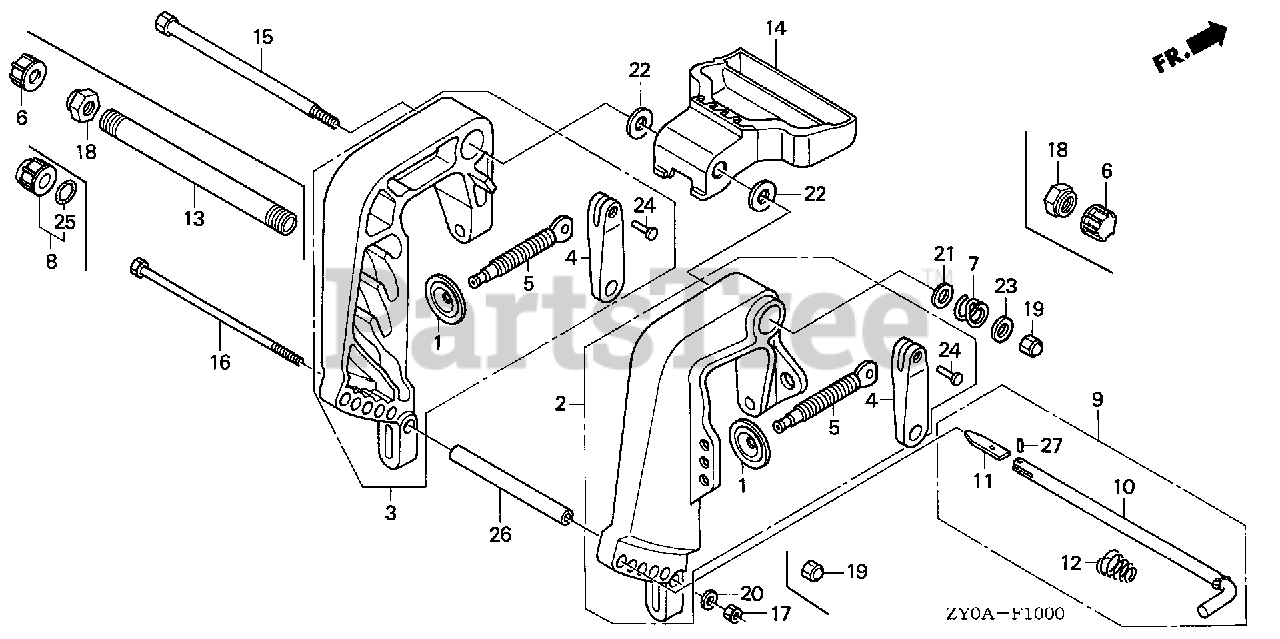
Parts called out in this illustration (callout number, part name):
1	PLATE, PUSH
2	BRACKET, R. STERN *NH282MU* (OYSTER SILVER METALLIC-U)
3	BRACKET, L. STERN *NH282MU* (OYSTER SILVER METALLIC-U)
4	GRIP, CLAMP
5	SCREW, CLAMP
7	SPRING, TILT
9	ROD, ADJUSTING
10	ROD, ADJUSTING
11	STOPPER, ROD
12	SPRING, ADJUSTING ROD
14	HANDLE, CARRYING
15	BOLT, TILTING
16	BOLT, HEX. (6X160)
17	NUT, HEX. (6MM)
19	NUT, SELF-LOCK (8MM)
20	WASHER, PLAIN (6MM)
21	WASHER, PLAIN (10MM)
22	WASHER (10MM)
23	WASHER (8MM)
24	RIVET (4X22.6)
26	COLLAR, DISTANCE (6MM)
27	PIN, SPRING (2X8)
